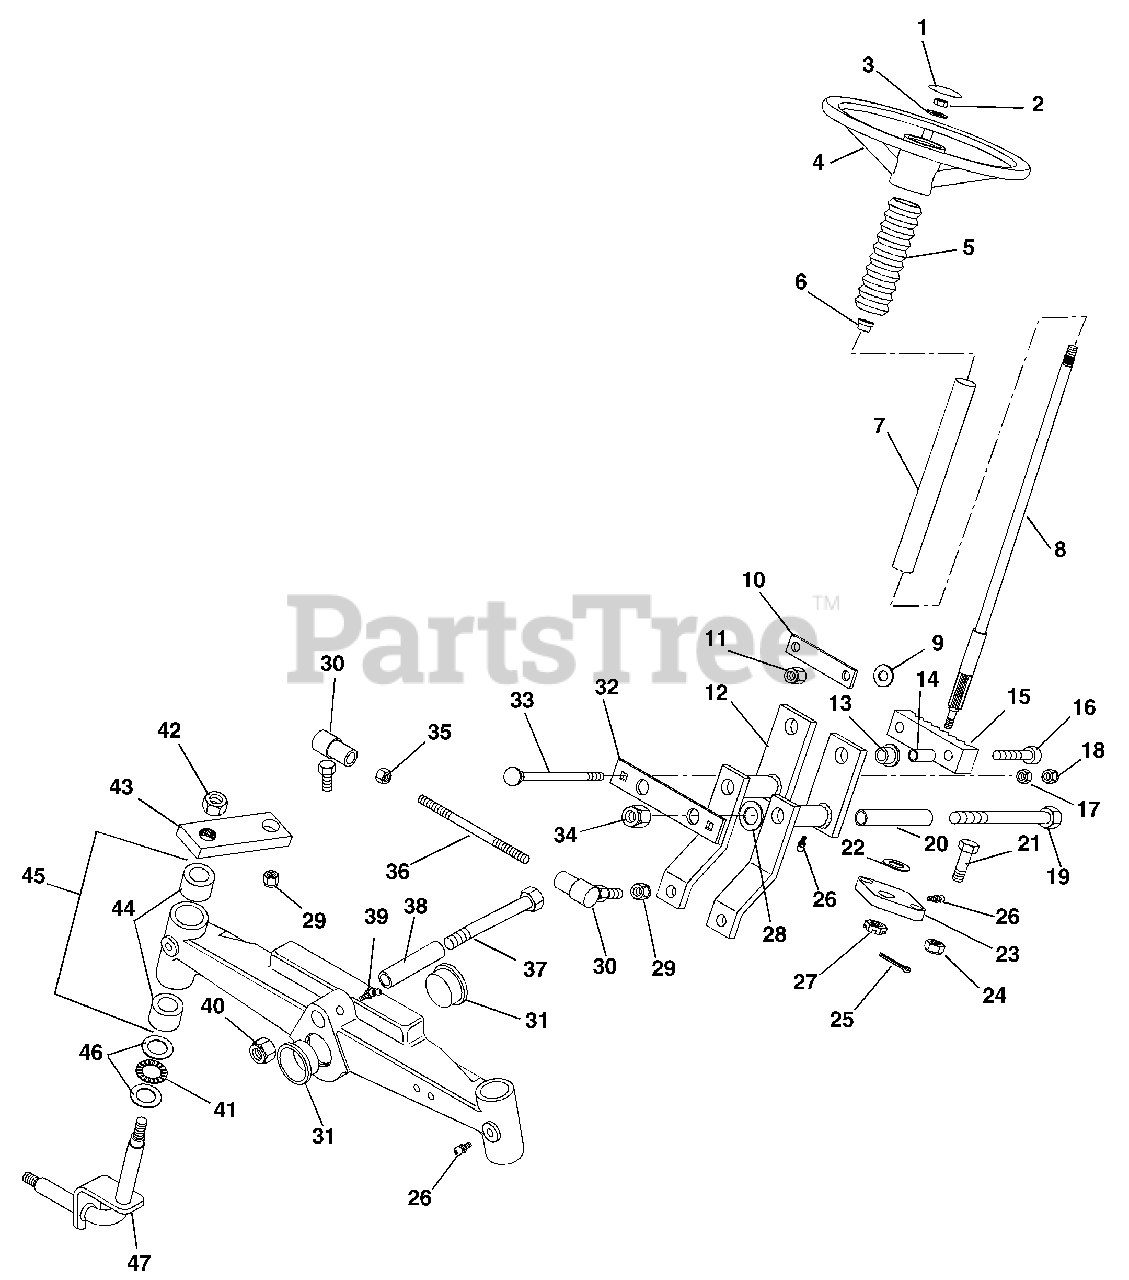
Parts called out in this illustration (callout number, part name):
1	Cap, Steering Wheel
2	Nut-Jam .63-11
3	Washer-Flat-Steel .67 x 1.31 x .095
4	Steering Wheel
5	Boot, Steering Column
6	Bushing-Flange .77 x 1.00 x .58 x 1.48 Nylon
7	Tube, Plastic 1.00 I.D.
8	Weldment, Steering Shaft
9	Washer-Flat-Steel .38 x .88 x 75 x .083
10	Strap, Rack and Pinion
11	Nut-Locking-Center .38-16
12	Weldment, Steering
13	Bushing-Flange .63 x .88 x .47 x 1.12
14	Bushing, Steel .39 x .62 x .68
15	Grade, Rack
16	Bolt-Hex .38-16 x 2.00 Grade 5
17	Nut-Hex .31-18
18	Nut-Locking-Center .31-18
19	Bolt-Hex .50-13 x 6.00 Grade 5
20	Sleeve,Pivot
21	Bolt-Hex .44-14 x 1.50 Grade 5
22	Washer-Thrust .51 x .92 x .031
23	Support, Steering Shaft
24	Nut-Locking-Center .44-14
25	Pin-Cotter .09 x 1.00
26	Fitting-Lube .25-28 x .26
27	Nut-Hex-Slotted .50-13
28	Washer-Hardened-Thrust .76 x 1.25 x .094
29	Nut-Locking-Nylon .38-24
30	Joint, Ball
31	Cap, Front Axle
32	Plate, Adjustment
33	Bolt-Round Head Square Neck .31-18 x 5.50 Grade 5
34	Nut-Locking-Center .50-13
35	Nut-Jam .38-24
36	Rod, Steering
37	Bolt-Hex .75-10 x 4.50 Grade 5
38	Tube, Axle Pivot
39	Fitting-Lube 45 Degree
40	Nut-Locking-Center .75-10
41	Bearing-Thrust .88 x 1.43 x .078
42	Nut-Hex .62-11
43	Arm, Tie Rod Axle
44	Bushing-Sleeve .87 x 1.00 x 1.00
45	Axle, Steering
46	Washer-Thrust .88 x 1.43 x .032
47	Weldment, King Pin
